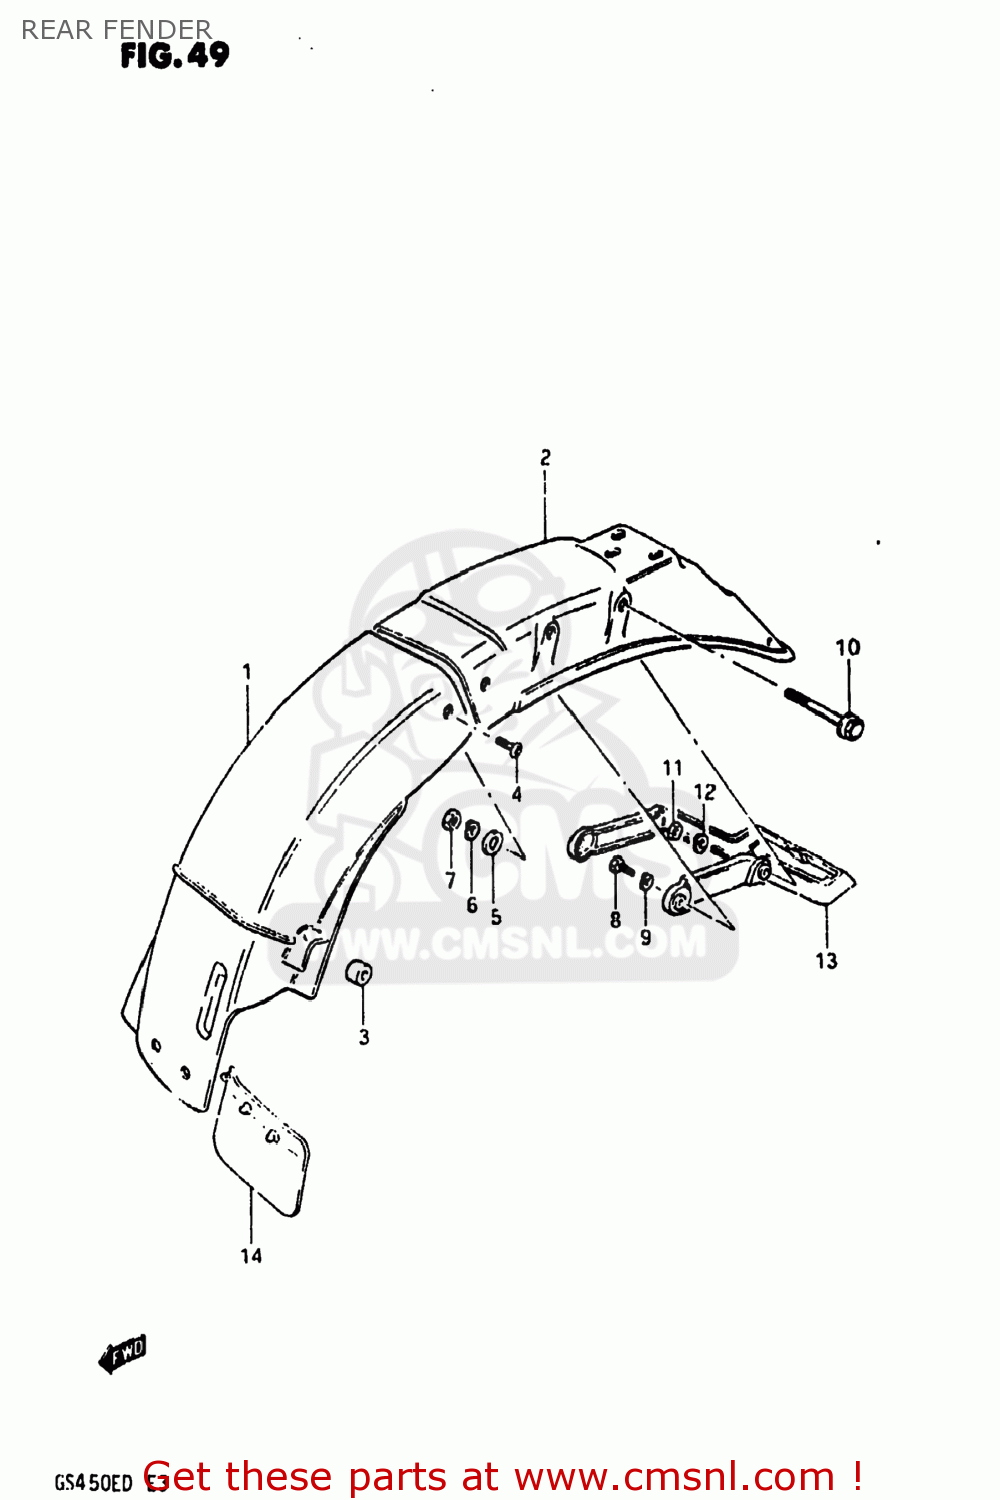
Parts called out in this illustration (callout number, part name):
1	FENDER,REAR
2	BODY,REAR FENDER,REAR
3	CUSHION
4	SCREW
5	WASHER (5.5X16X1.2)
6	LOCK WASHER
7	NUT
8	BOLT, UPPER
9	LOCK WASHER
10	BOLT
11	NUT
12	LOCK WASHER
13	REINFORCEMENT,REAR FENDER
14	GUIDE,RR FENDER MUD
